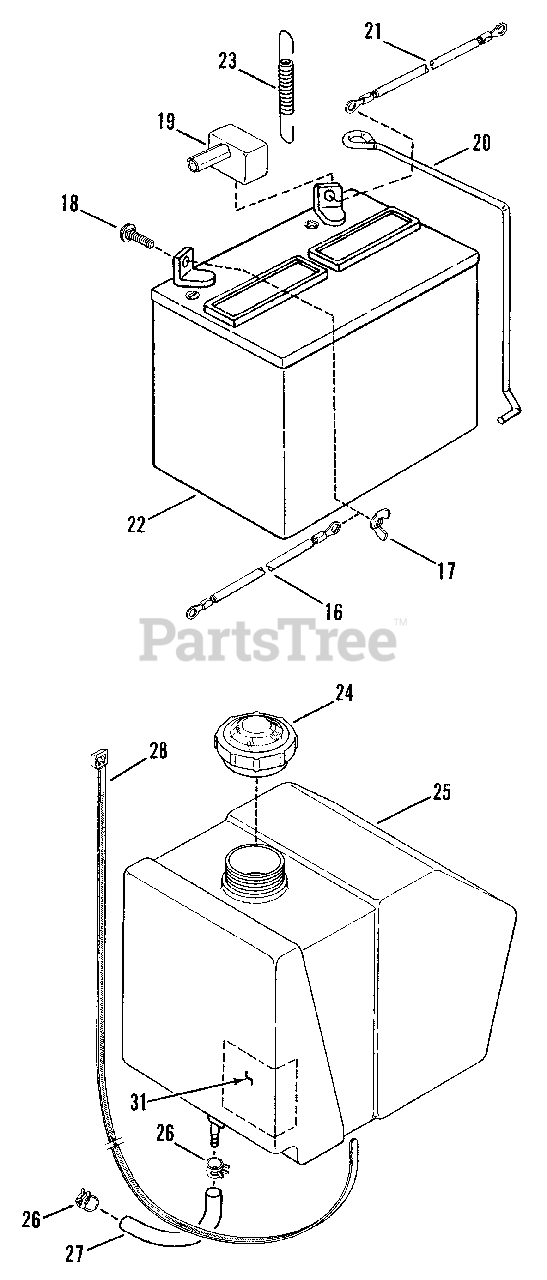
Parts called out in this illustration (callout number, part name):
16	CABLE, Negative Terminal
17	WING-NUT, 1/4-20
18	BOLT, 1/4-20 x 3/4" Short Neck Carriage
19	COVER, Positive Terminal
20	CLAMP, Battery
21	CABLE, Positive Terminal
22	KIT, Battery, 12 Volt
23	SPRING, Battery Bracket
24	CAP, Fuel Tank
25	TANK, Fuel
26	CLAMP, Fuel Line
27	LINE, Fuel (14.5" Long)
28	CABLE-TIE, Fuel Tank Hold Down
31	HEAT SHIELD, Fuel Tank
